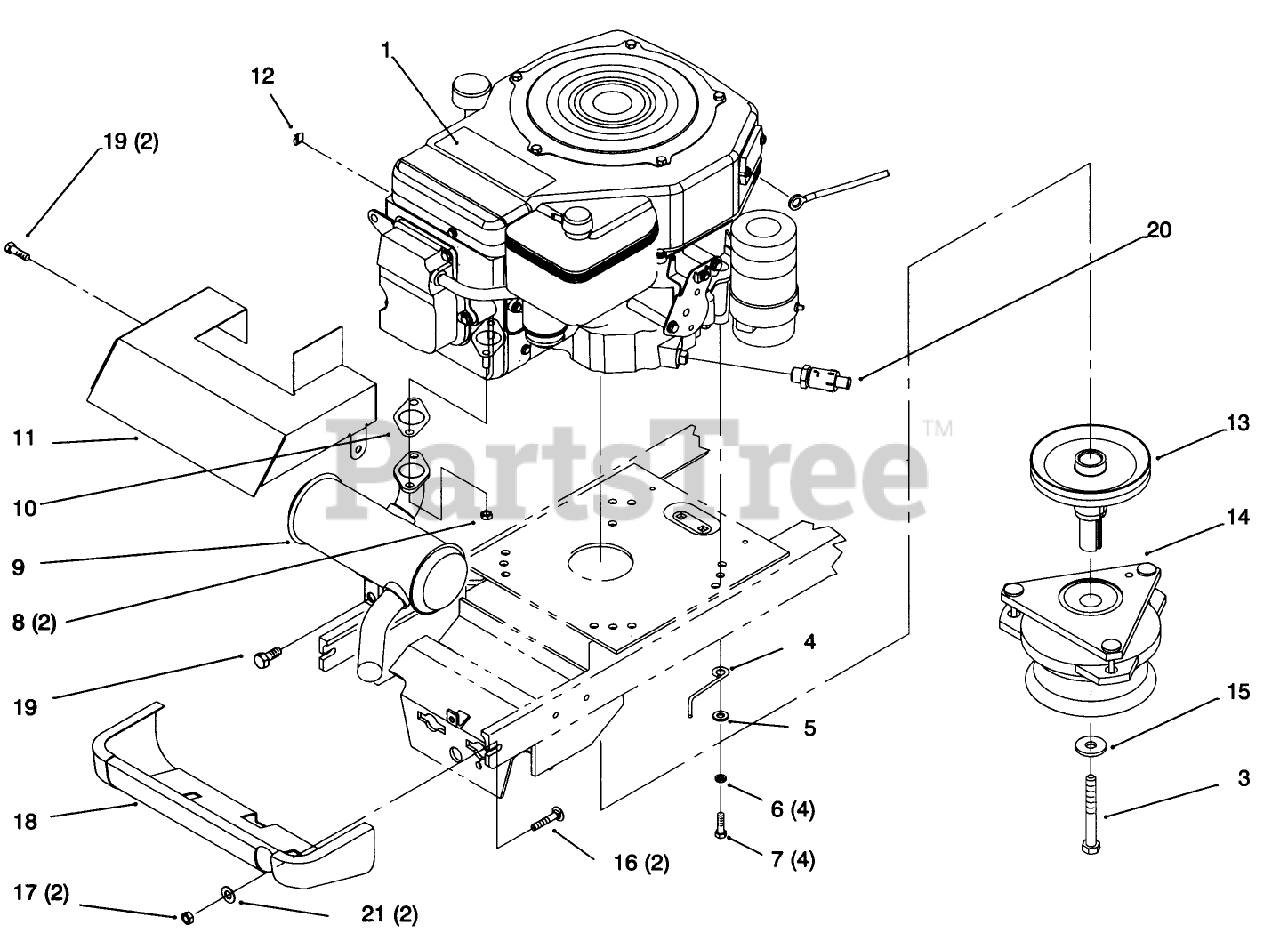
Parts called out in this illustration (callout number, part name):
1	DECAL - ENGINE
3	HHCS-M10X1.5X110 ESL
4	GUIDE-BELT
5	WASHER-PLAIN
6	WASHER-LOCK
10	KOHLER 12-041-03
11	SHIELD-MUFFLER
12	CLIP-RETAINER, WIRE
13	PULLEY-ENGINE
13	PULLEY- ENGINE GEAR
14	CLUTCH - ELEC PTO
15	WASHER
16	SCREW-CARR
17	NUT-LOCK, NI
19	SCREW
20	VALVE-DRAIN, OIL
21	WASHER-FLAT
